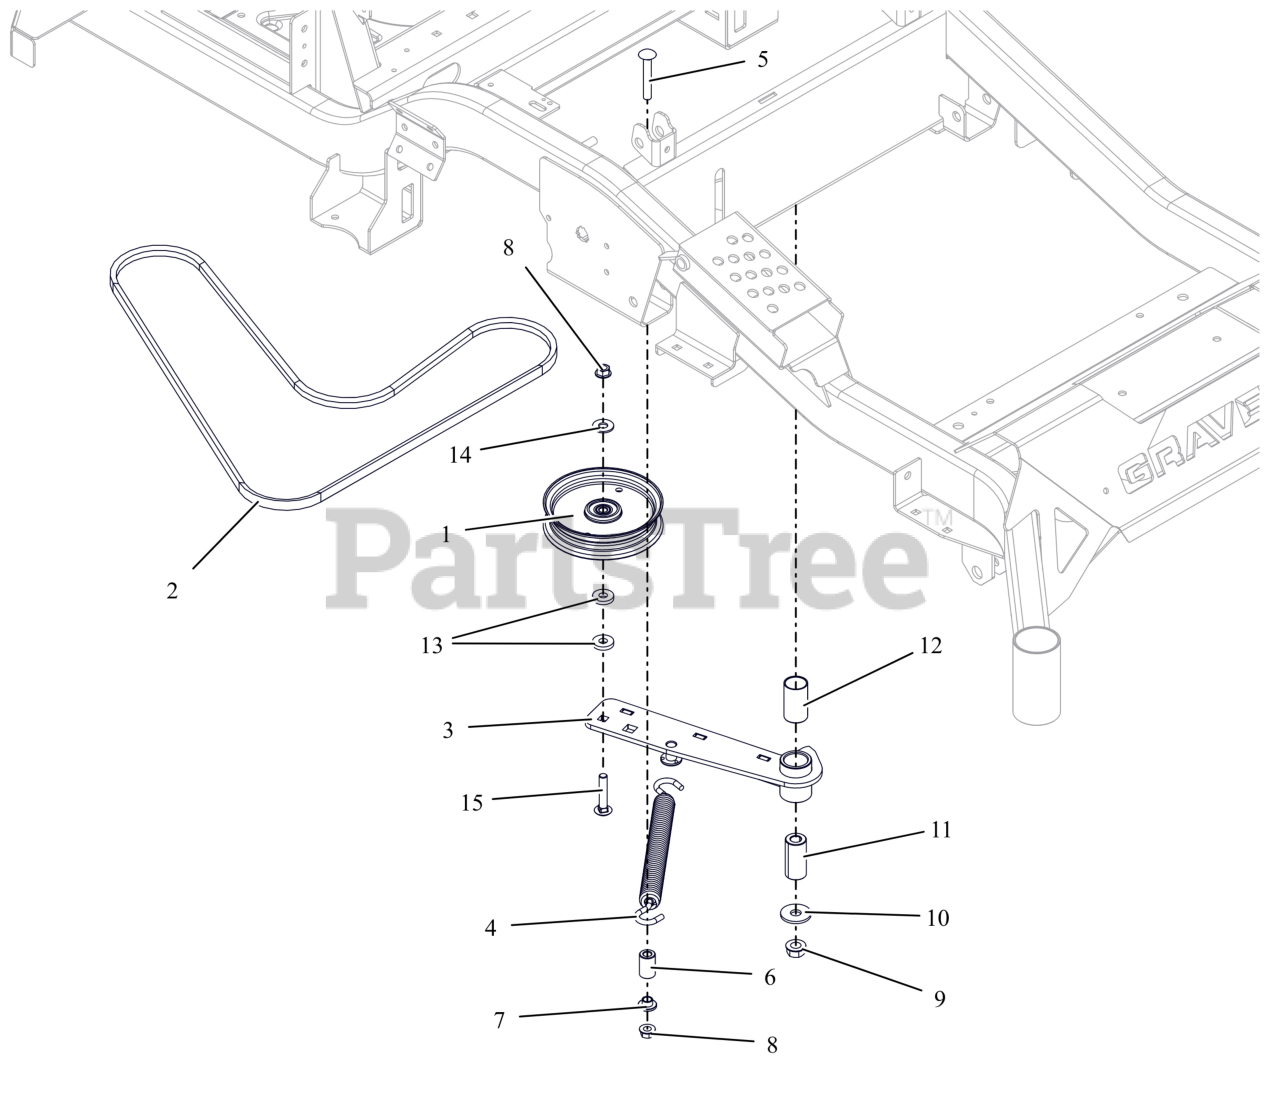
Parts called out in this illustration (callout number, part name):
1	IDLER- FLAT - 5.00" X .75"
2	V-BELT, 4L-WRAPPED
3	WLDMT, HYDRO DRIVE IDLER ARM (BLACK)
4	SPRING, EXTENSION
5	BLT, RHSSN.38-16X2.50 G5 ZCC
6	BUSHING, SLV .380X.750X1.190
7	BSHG-FLG .385X.500X.875X.406
8	NUT-LK-TOP-FLG .38-16 ZC120
9	NUT-LK-TOP-FLG .500-13 GF ZCC
10	WSHR-FL-STL.511X1.44X.125ZC120
11	BSHG, SPCR .502X.997X2.03 PM
12	BSHG, 1.00X1.125X1.937
13	WSHR, FLT .406X1.00X.188 ZCC
14	WSHR,FLT .438X1.00X.083 ZCC
15	BLT, RHSN .38-16X2.00 G5 ZCC
